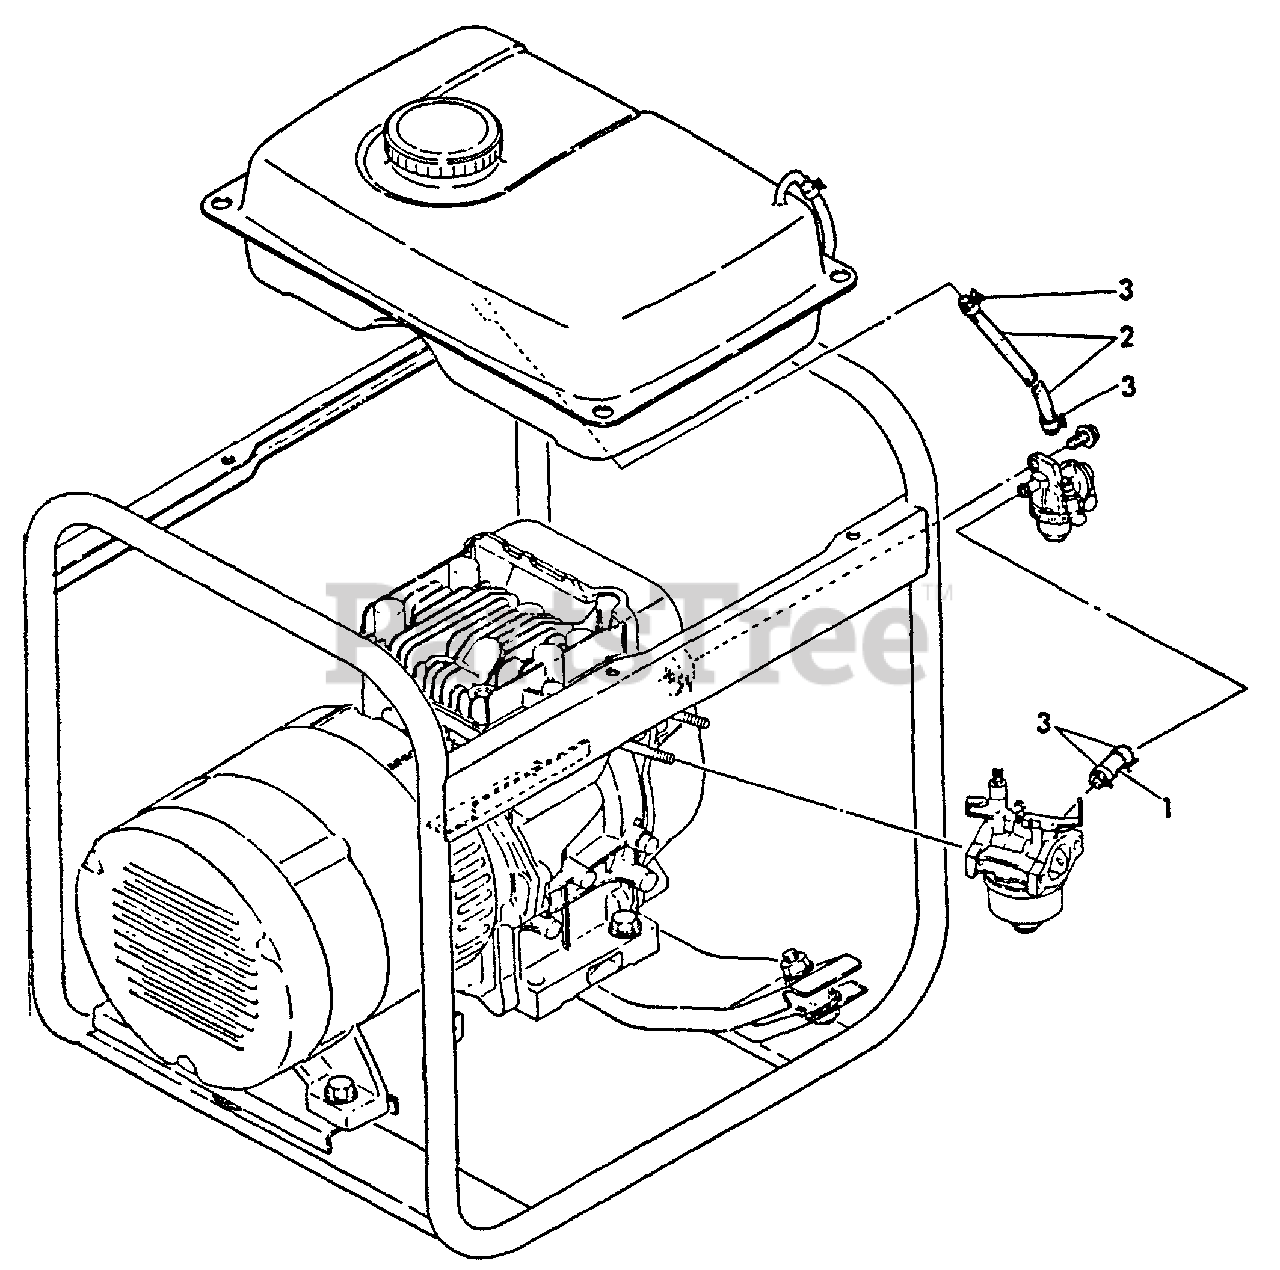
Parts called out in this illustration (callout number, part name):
1	PIPE - FUEL
2	PIPE - FUEL
3	CLAMP, HOSE - 10
